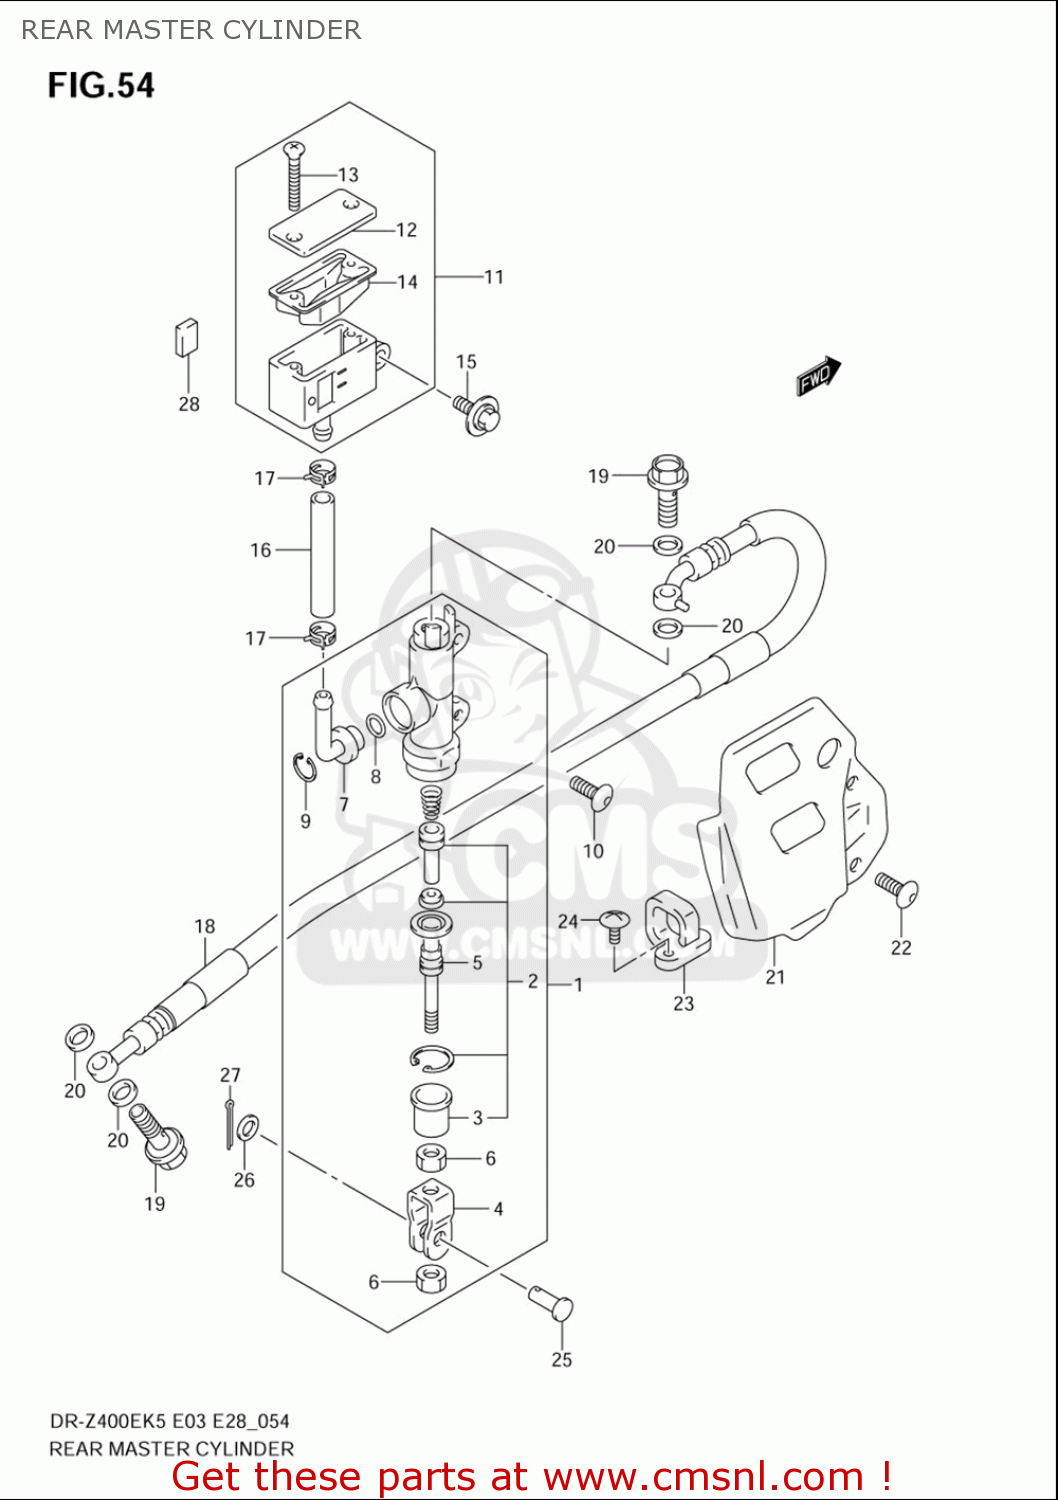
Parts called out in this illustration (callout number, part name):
1	CYLINDER ASSY,RR MASTER
2	PISTON/CUP SET
3	BOOT
4	YOKE
5	ROD,PUSH
6	NUT
7	CONNECTOR
8	O RING
9	CIRCLIP
10	SCREW(6X16)
11	TANK ASSY,RESERVOIR
12	CAP
13	SCREW
14	DIAPHRAGM
15	BOLT(6X16)
16	HOSE,FR RESERVOIR TANK
17	CLAMP,RESERVOIR HOSE
18	HOSE COMP,REAR BRAKE
19	BOLT UNION
20	WASHER(10X15X1.5)
21	GUARD,RR MASTER CYLINDER
22	SCREW(6X16)
23	GUIDE,RR BRAKE
24	SCREW
25	PIN(8X20)
26	WASHER (8.5X14X1.6)
27	PIN
28	CUSHION,RR RESERVOIR TANK
